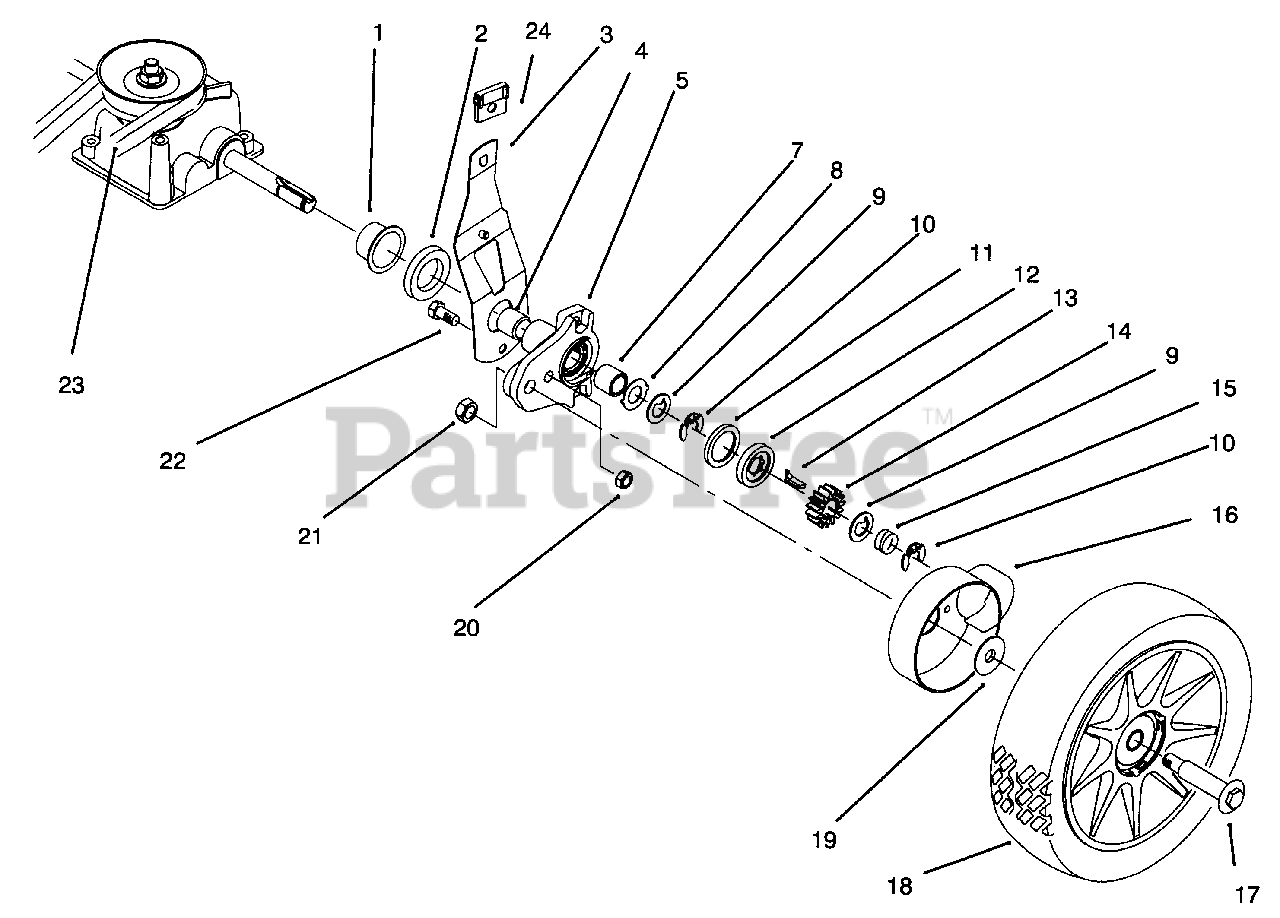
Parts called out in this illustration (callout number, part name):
2	Spacer Axle Shaft
3	Spring Arm Ass'y
5	Pivot Arm Ass'y-Rear
8	Washer-Thrust Pivot Arm
9	Washer-Thrust, Keyed
10	Ring-Klip
11	Ring-Friction
12	Washer-Clutch, Plastic
13	Key-Rocking LH
14	Gear-Pinion
15	Spring-Compression
16	Cover Wheel
17	Bolt-Wheel
18	Wheel Assy.-8"
19	Washer-Stepped
23	"V" Belt
